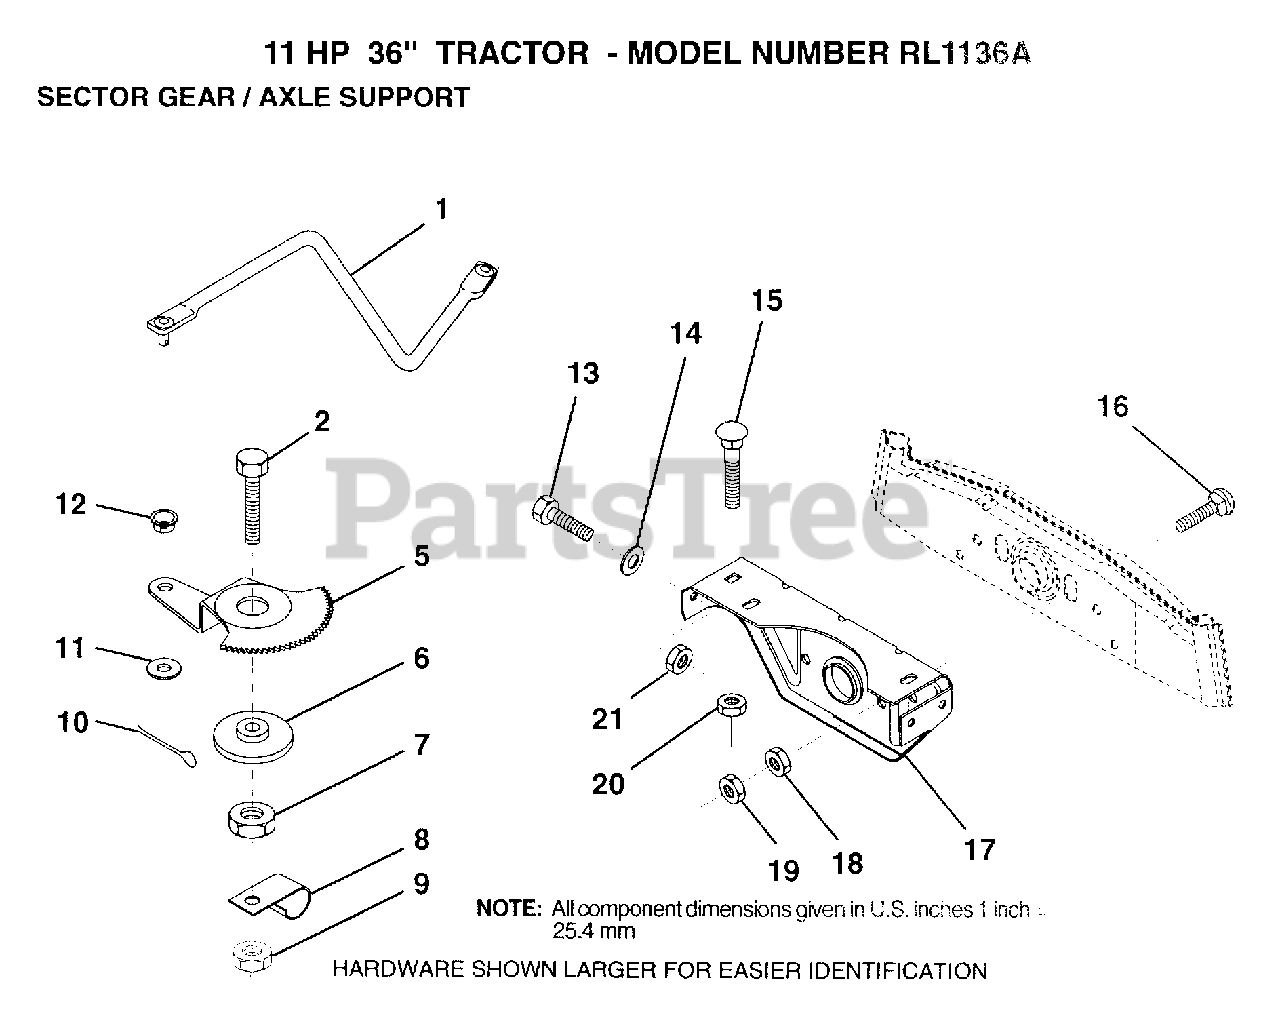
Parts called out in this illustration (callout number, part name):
1	DRAG LINK
2	"BOLT,HEX"
5	GEAR SECTOR
6	BUSHING
7	NUT
8	CLIP INSULATOR
9	NUT LTV
10	COTTER PIN
11	WASHER
12	BUSHING.DRAGLINK
13	BOLT
14	WASHER
15	BOLT
16	BOLT
17	"SUPT,FRT AXLE"
18	NUT.HEX.3/8-16UNC
19	LOCKNUT
